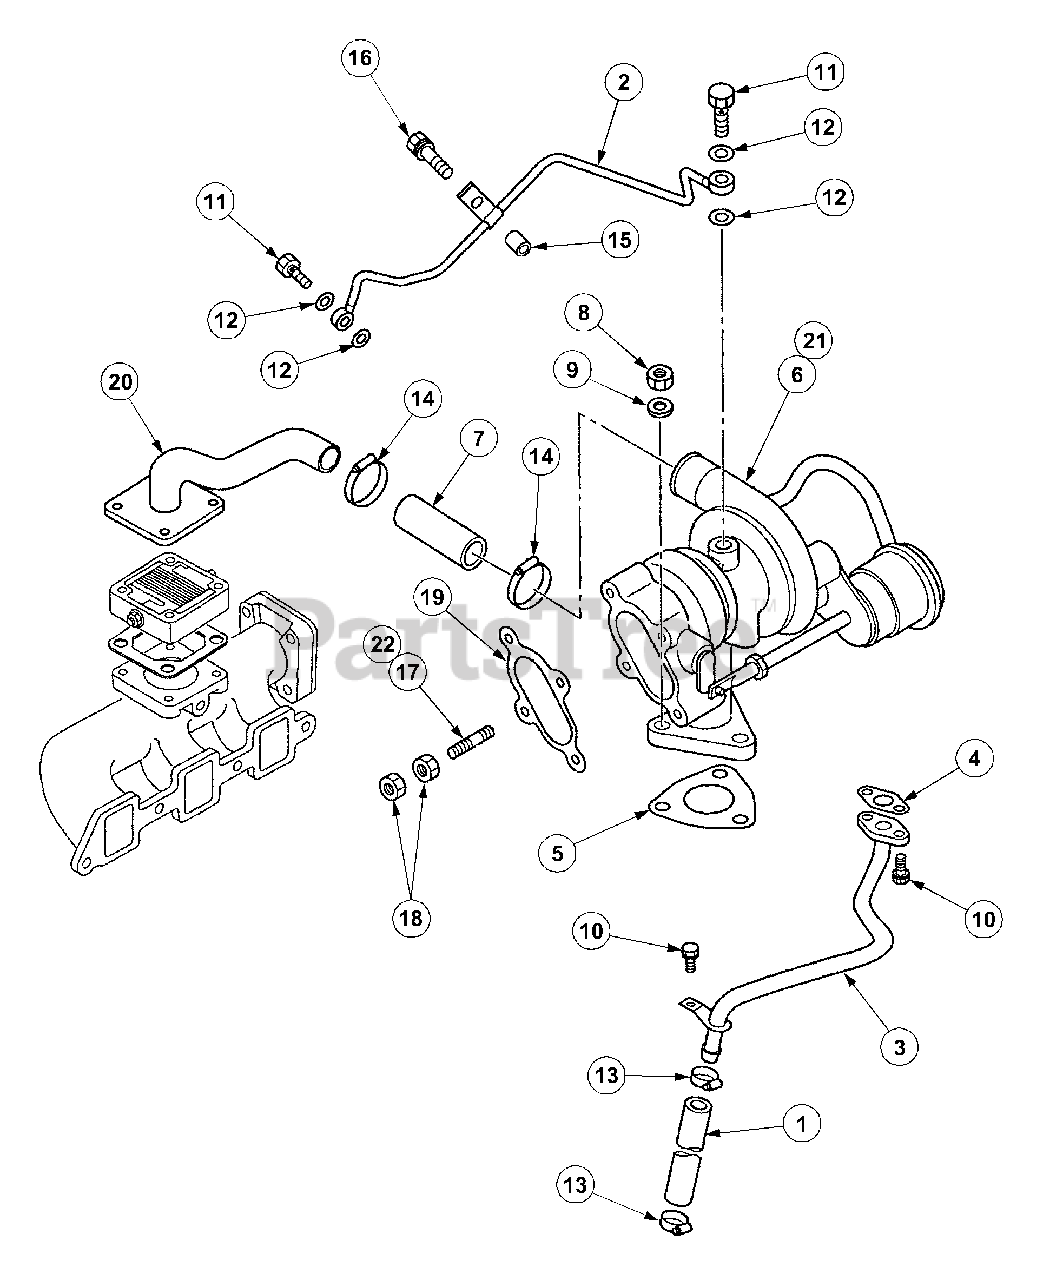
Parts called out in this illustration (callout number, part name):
2	Pipe Assy,Oil
3	Pipe,Oil Return
4	Gasket,Oil Pipe
8	Nut
9	Washer,Plain
10	Bolt,w/Washer
12	Gasket
15	Spacer
16	Bolt,w/Washer
20	Pipe,Air Heat
21	Turbocharger
22	Stud
